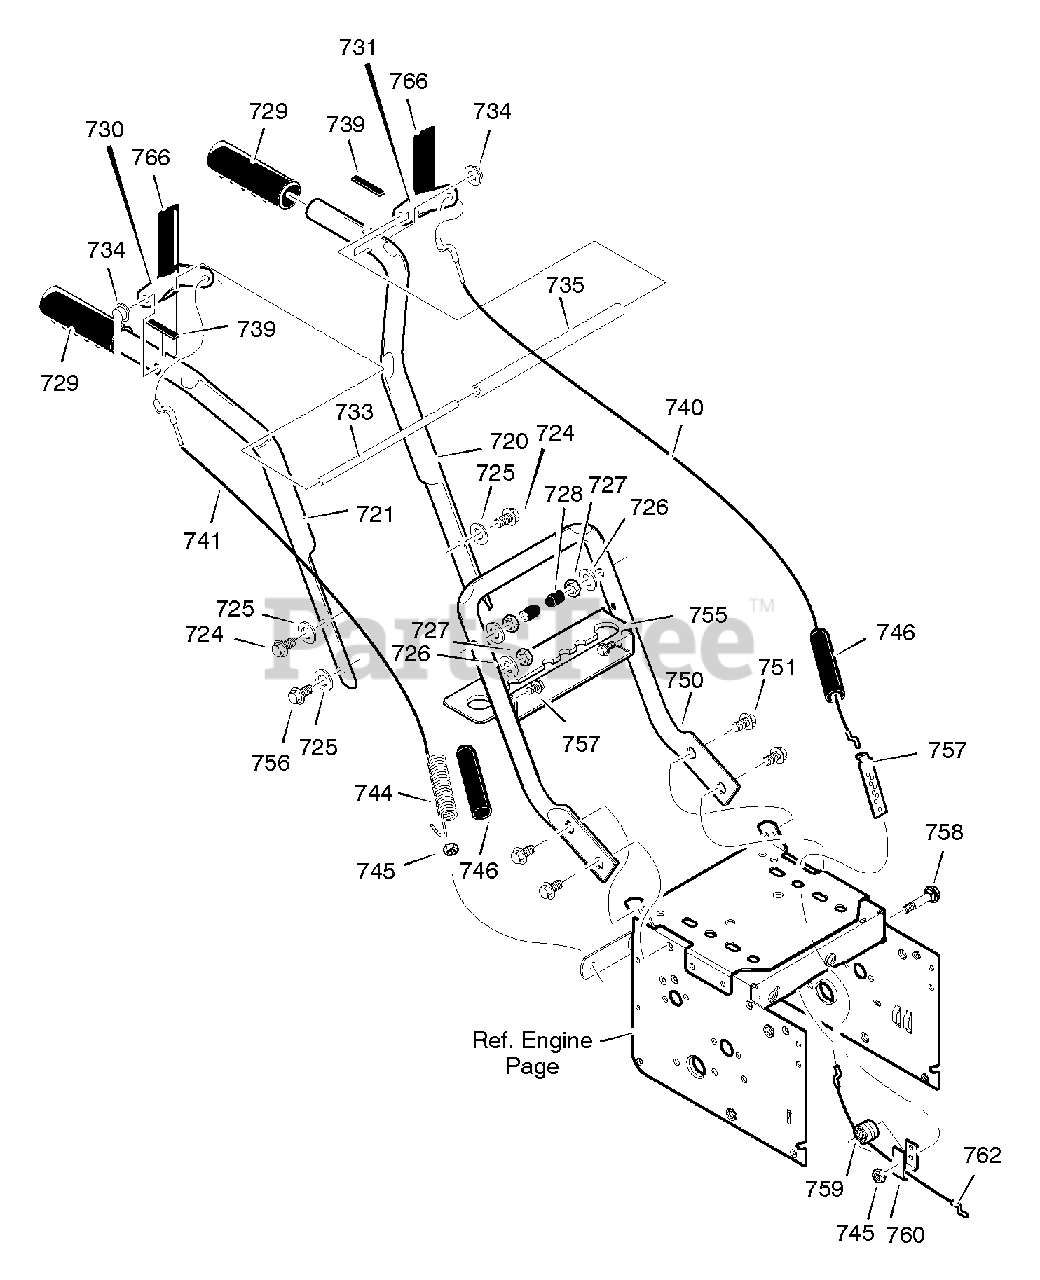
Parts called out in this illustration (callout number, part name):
720	HANDLE, UPPER LH
721	HANDLE, UPPER RH
724	SCREW, 5/16-18 x 2.75
725	WASHER, FLAT
726	WASHER, SPTLK .31X.58X.08
727	NUT, 5/16-18 REGHEX YZ
728	STOP, RED PLASTIC
729	GRIP-HANDLE FINGER
730	LEVER, ASSY CLUTCH DRIVE RH
731	LEVER, ASSY CLUTCH DRIVE LH
733	ROD, PIVOT CLUTCH
734	NUT, PUSH ON CAP
735	SPACER-HANDLE
739	BUMPER, RECTANGLE
740	CABLE, CLUTCH
741	CABLE, AUGER CLUTCH
743	BRACKET, CABLE ADJUSTER
744	SPRING, AUGER CLUTCH
745	NUT, 1/4-20 NYLOCK YZ
746	BOOT, CABLE SPRING
750	HANDLE, LOWER
751	SCREW, TAP 5/16-18 X .75
755	BRKT, GEAR SELECTOR
756	SCREW, 5/16-18 x 2.00
757	PLATE, ADJUSTING
758	BOLT, HEX 1/4-20 X 1.50
759	SPOOL-CABLE, AUGRT CLUTCH
760	BRACKET, CABLE SPOOL YZ
762	CABLE, LOWER DRIVE 12"
766	GRIP, CLUTCH HANDLE
